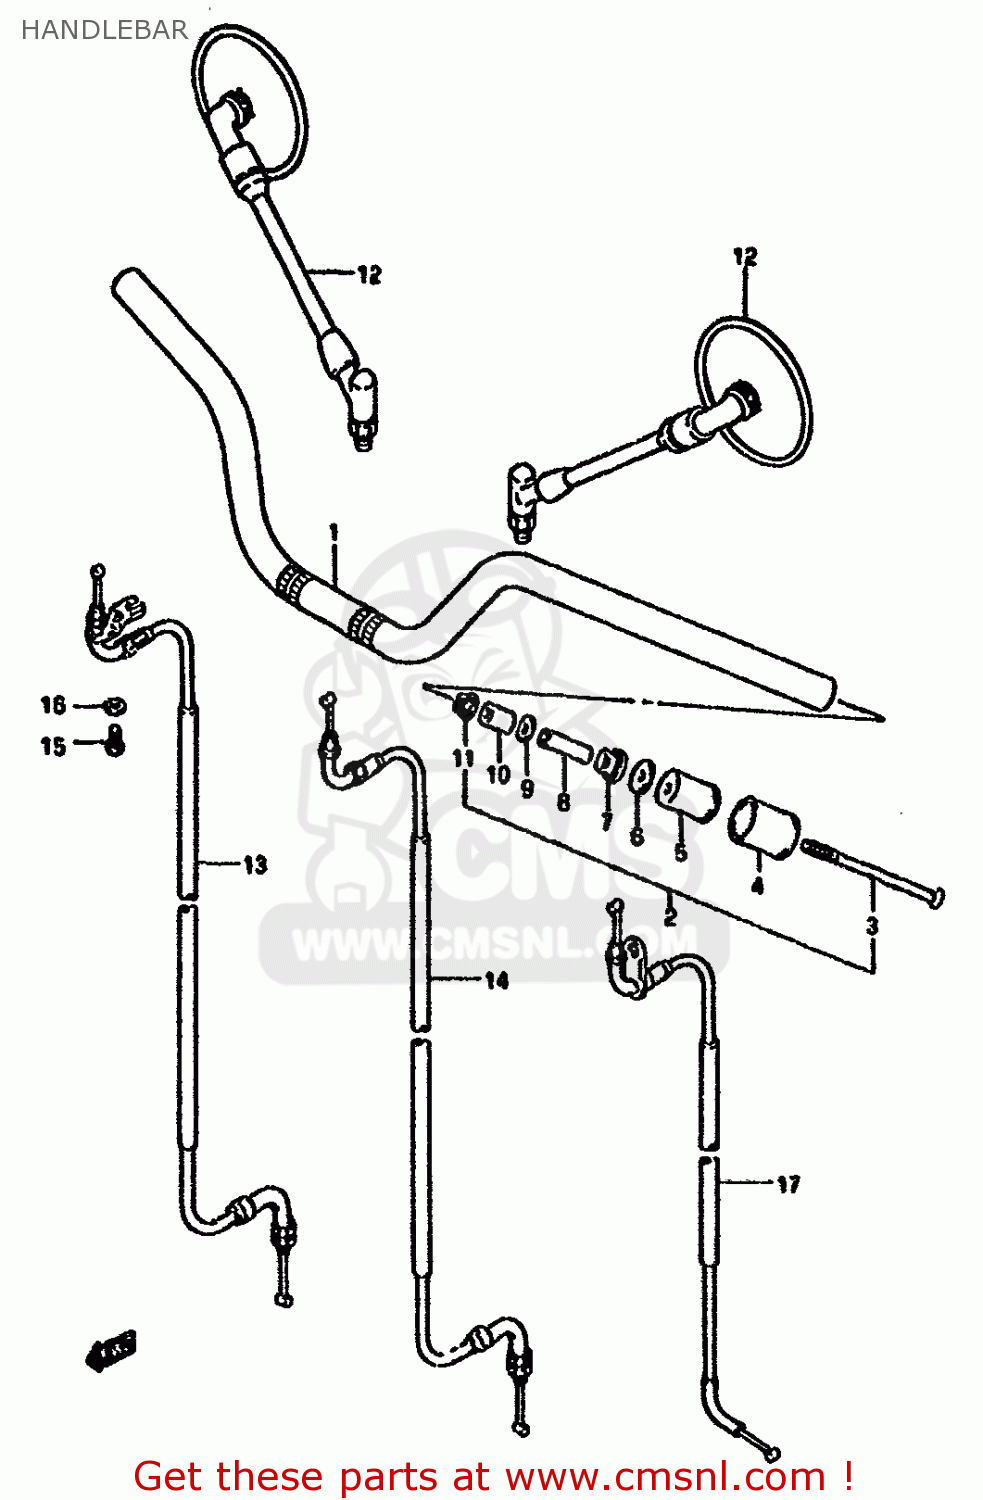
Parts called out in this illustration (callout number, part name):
1	HANDLEBAR
2	BALANCER SET
3	SCREW(6X110)
4	CAP,BALANCER
5	BALANCER,HANDLEBAR
6	SPACER,BALANCER
7	EXPANDER,HANDLE BALANCER NO.2
8	SPACER
9	WASHER
10	EXPANDER,HANDLE BALANCER
11	NUT
12	MIRROR ASSY,RH
13	CABLE ASSEMBLY,THROTTLE
14	CABLE ASSEMBLY,THROTTLE
15	SCREW
16	WASHER,LOCK
17	CABLE,STARTER
